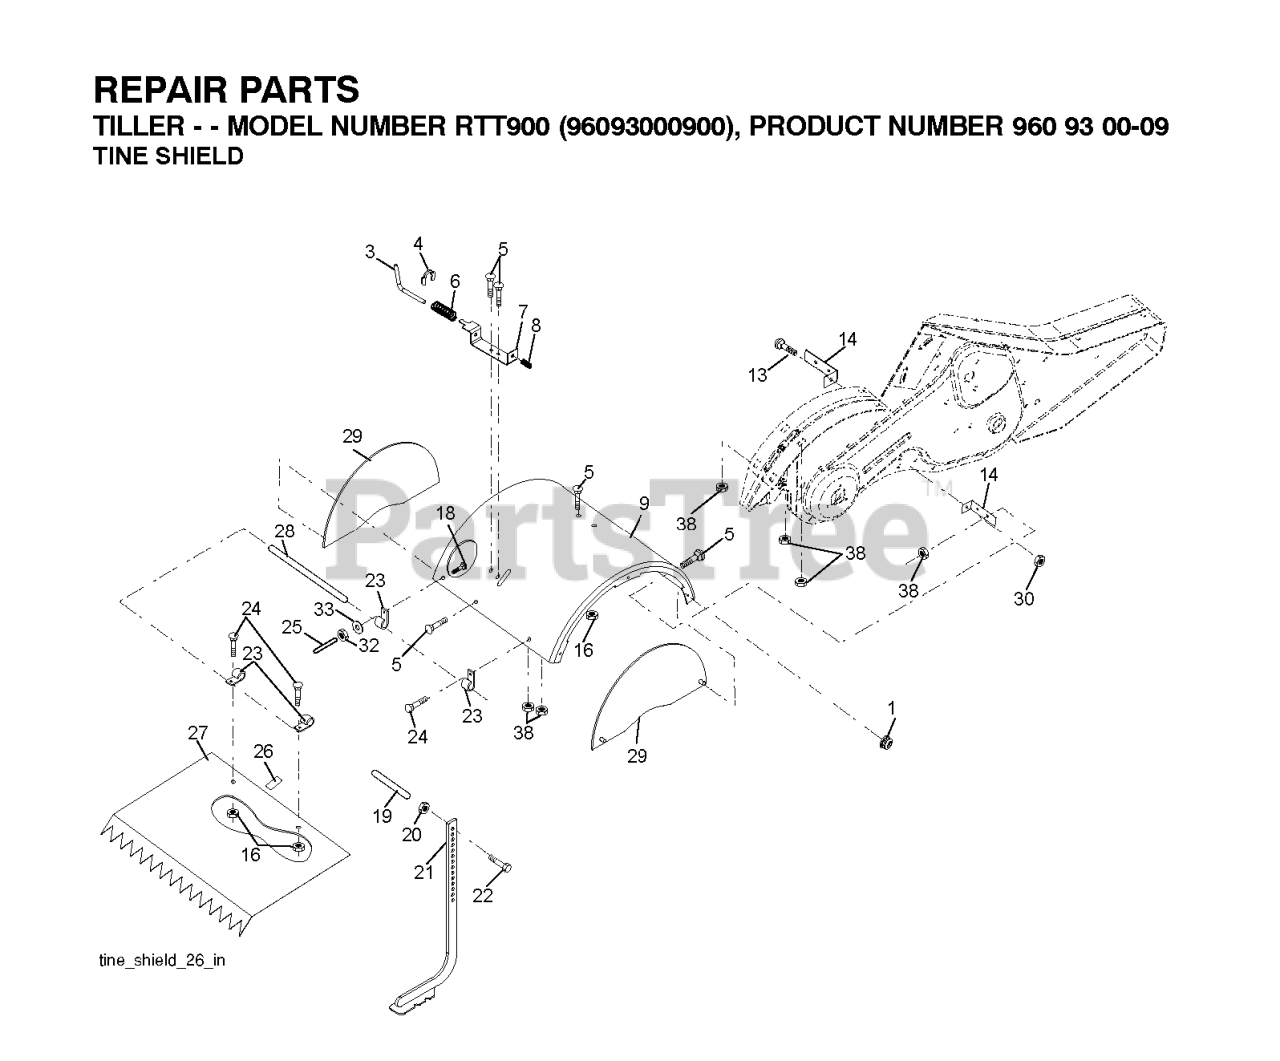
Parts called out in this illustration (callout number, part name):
1	NUT LOCK HEX FLANGE 5/16-18
3	STAKE PIN TI
4	RING, KLIP
5	BOLT, RDHD SQNK 5/16-18 X 3/4
7	BRACKET.LATCH.STAKE.3.20.BLACK
8	SPRING CRT
9	SHIELD.TILLER.TINE.ORANGE
13	BOLT.CARRIAGE.5/16-18
14	BRACKET.TINE.SHIELD.TILLER
16	NUT T
20	NUT.HEX.3/8-16UNC
21	STAKE.DEPTH.16.CRT.BLACK
22	BOLT.375-16
25	VINYL CAP TI
26	PAD IDLER TI
27	SHIELD.PNT.LEVEL.CRT.14.MS-668
28	PIN.HINGE.TILLER
29	SHIELD.ASM.SIDE.ORANGE.(OLD)
30	LOCKNUT-FLANGE 5/16-18
32	NUT
33	LOCKWASHER
38	NUT
